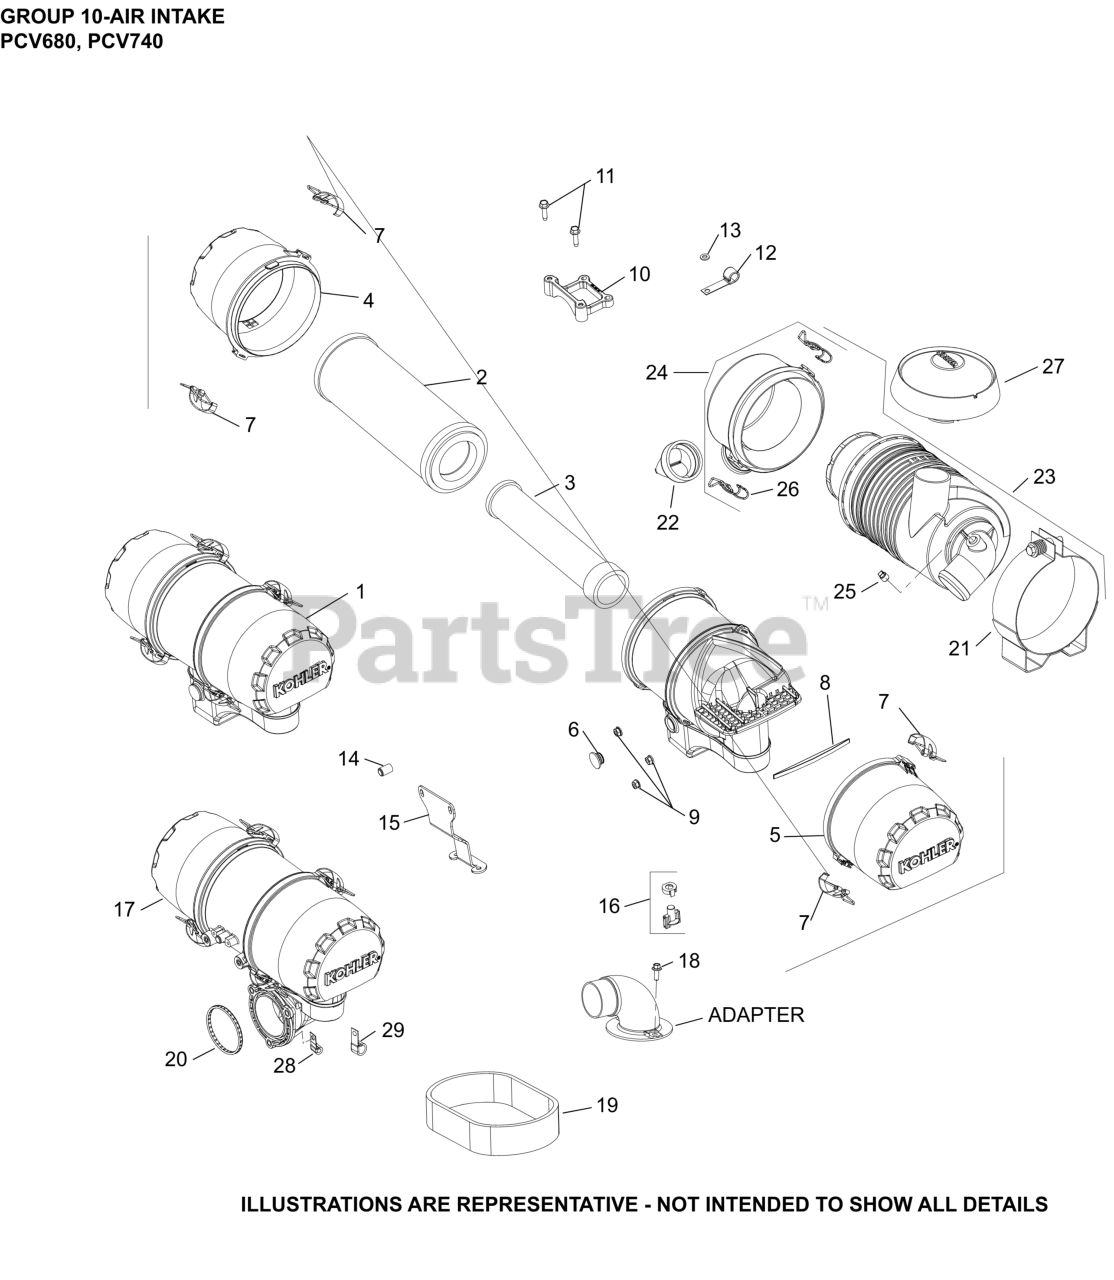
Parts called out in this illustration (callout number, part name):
2	ELEMENT, AIR FILTER - PRIMARY
3	ELEMENT, AIR FILTER - SAFETY
4	COVER, AIR FILTER
5	COVER, RAIN CAP
6	PLUG, HOLE
7	CLIP ASSEMBLY
8	DAMPER, FOAM INSERT
9	NUT, FLG M6X1.0
12	CLIP, CABLE
13	WASHER, FLAT 1/4" (O.D. 1/2")
14	CAP, MASKING
15	BRACKET, SUPPORT
17	FILTER ASSEMBLY, AIR - OIL FILTER SIDE
18	SCREW, FLG M6X1.0X16
20	O-RING (HDAC SEAL-EFI)
29	CLIP, CABLE (KM)
